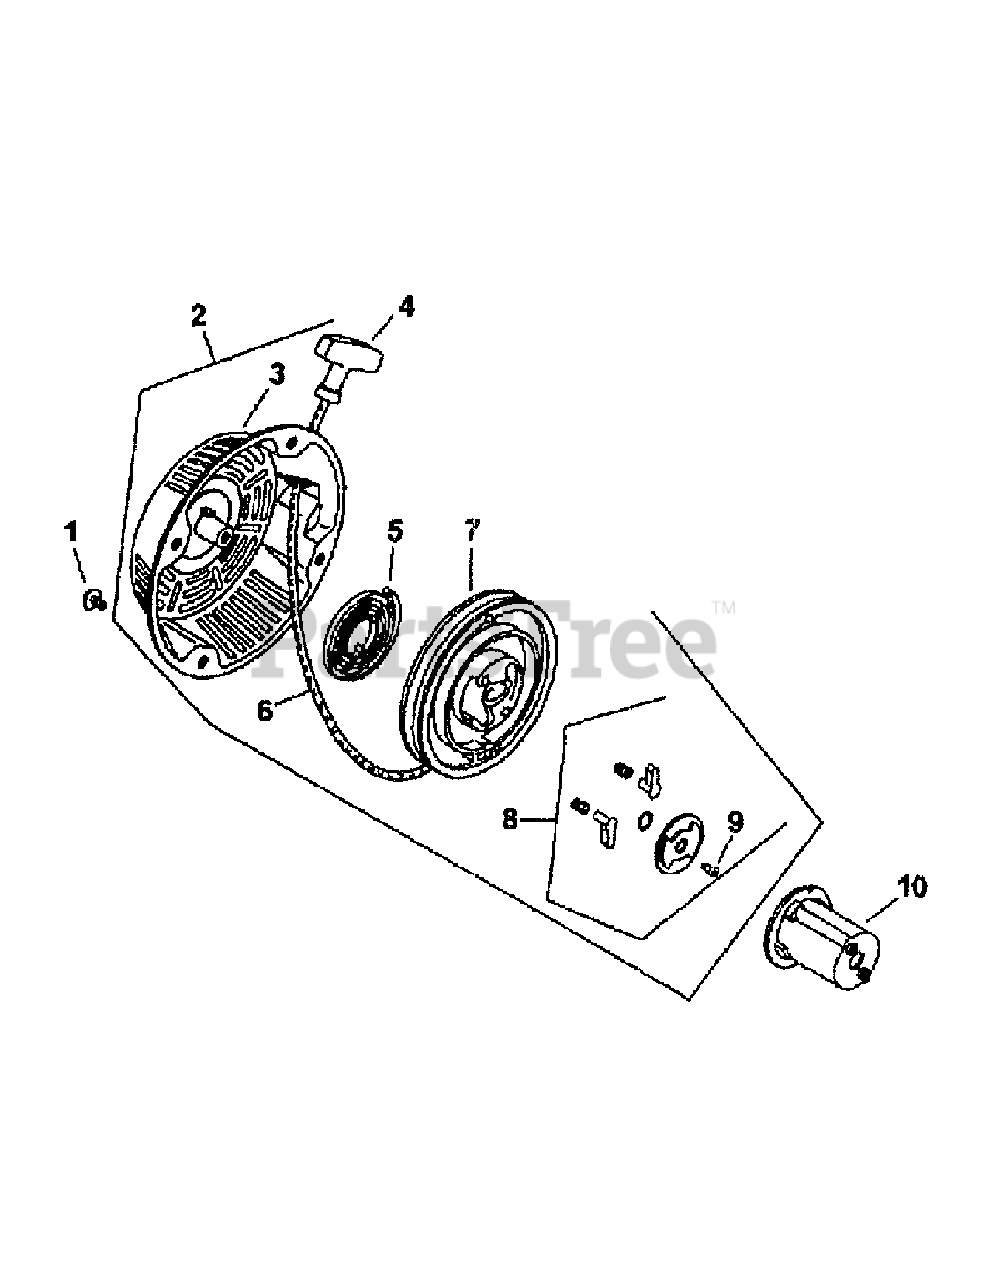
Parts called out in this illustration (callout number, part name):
2	Recoil Starter
3	Housing Assembly
4	Handle, Starter
5	Spring, Recoil
6	Rope, Starting
8	Kit, Pawl Repair
10	Cup, Starter Drive
